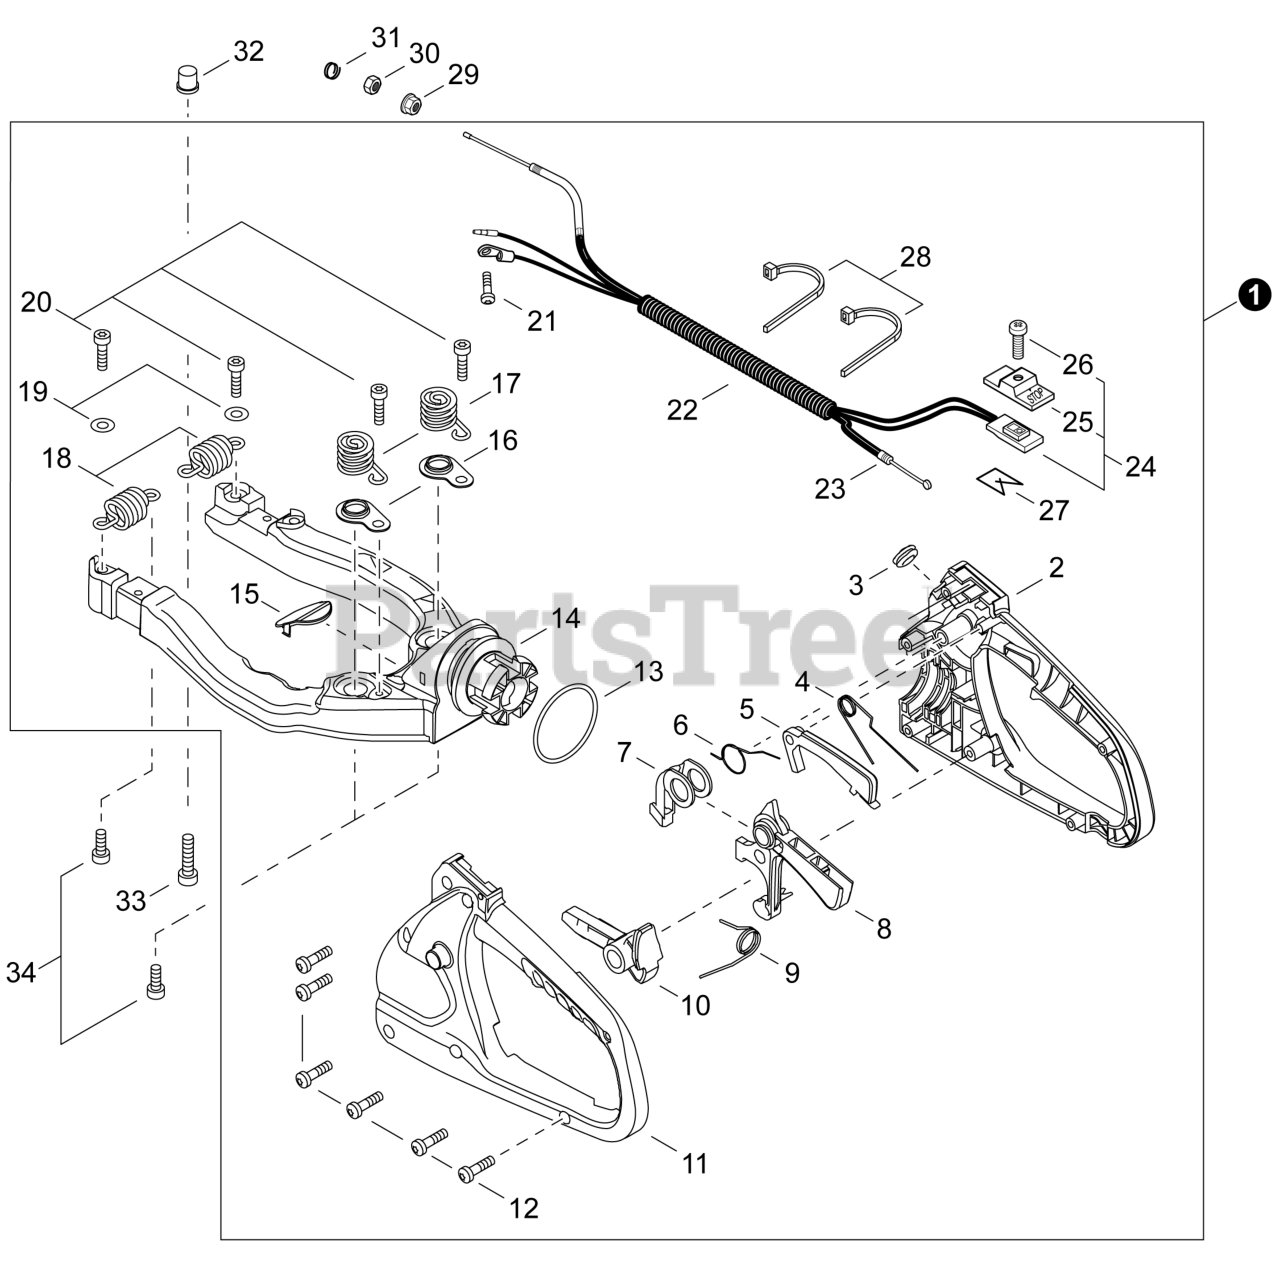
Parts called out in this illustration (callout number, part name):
1	HANDLE ASSY, REAR
2	HANDLE, RIGHT REAR
3	GROMMET
4	SPRING, TORSION
5	LOCKOUT, THROTTLE
6	SPRING, COIL
7	LEVER, THROTTLE
8	TRIGGER, THROTTLE
9	SPRING, TORSION
10	LEVER, HANDLE RELEASE
11	HANDLE, LEFT REAR
12	BOLT, TORX 4x16
15	COVER, HANDLE
16	HOLDER, SPRING
17	SPRING, COMPRESSION
18	SPRING, COMPRESSION
20	BOLT, TORX 6x20
21	BOLT, TORX 4x10
22	TUBE, PROTECTIVE
23	CABLE, THROTTLE
24	SWITCH, ON-OFF
25	KNOB, SWITCH - RED
26	SCREW 3x10
28	STRAP, CABLE
29	NUT, FLANGE M6
33	BOLT, TORX 6x25
34	BOLT, TORX 6
